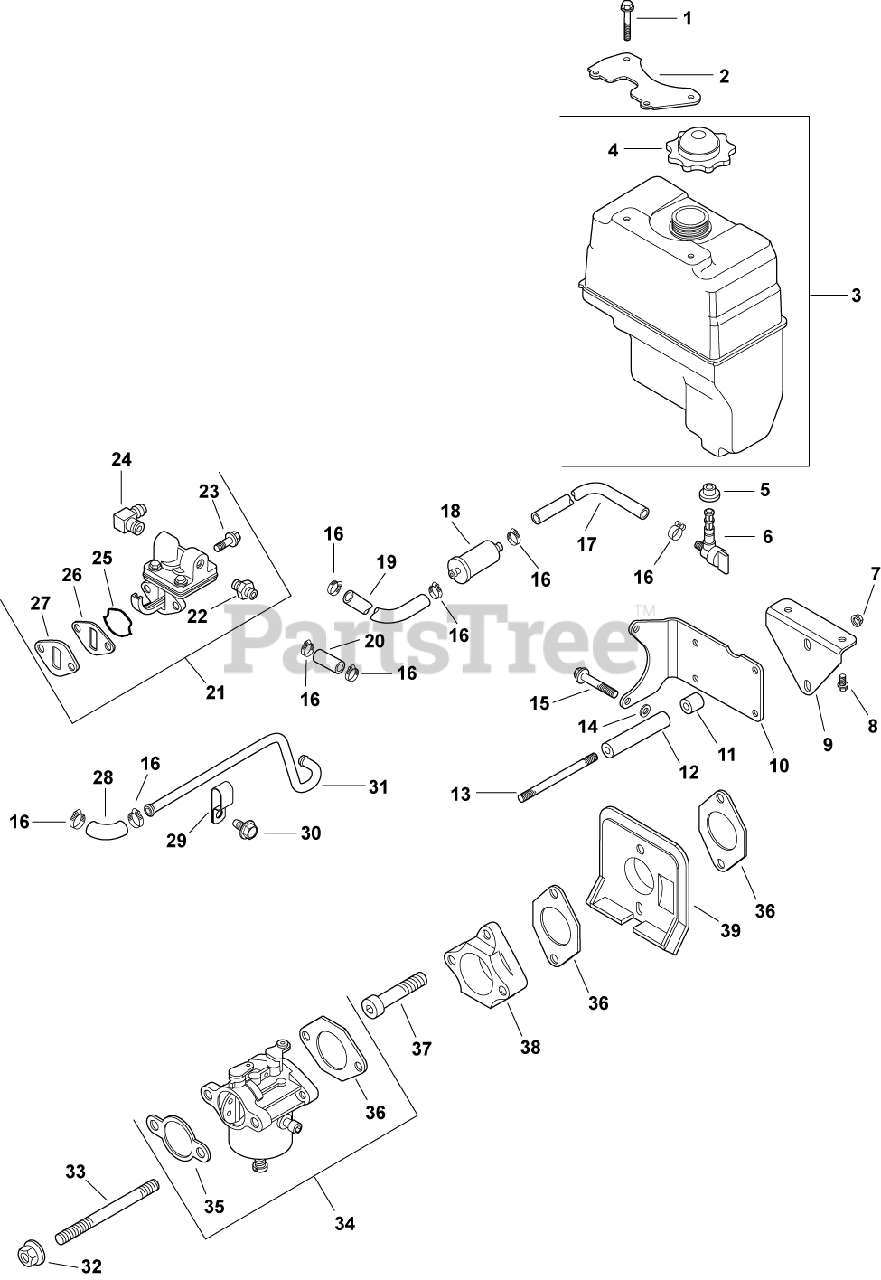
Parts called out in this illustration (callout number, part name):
1	SCREW,FLG THD FRM M6X1.0X25-(#25086395S)
2	BRACKET, FUEL TANK
3	KIT, FUEL TANK
4	CAP, FUEL TANK
5	BUSHING, FUEL TANK
6	VALVE, FUEL SHUT-OFF
7	NUT, FLG M8X1.25
8	SCREW, FLG M6X1.0X12
10	BRACKET, FUEL TANK
12	SPACER, FUEL TANK
13	STUD, M8X1.25X133-USE 25 755 54-S
14	WASHER, FLAT 11/32"
15	SCREW, FLG M8X1.25X50
16	CLAMP, HOSE (KM)-USE 25 237 31-S
17	LINE, FUEL 10"
18	FILTR,FUEL 75 MICRON (GRAVTY FEED)
19	LINE - DISCONTINUED
20	LINE - DISCONTINUED
21	KIT, FUEL PUMP
23	CONNECTOR
23	SCREW,FLG THD FRM M6X1.0X20-(#25086396S)
24	CONNECTOR, 90 DEG. HOSE
25	O-RING, FUEL PUMP
26	SPACER, FUEL PUMP
27	GASKET, FUEL PUMP
28	HOSE, FUEL LOW-PERMEATION
29	CLIP, TUBE & WIRING (KM)
30	SCREW, FLG THD FRM M5X.8X10
31	LINE, FUEL - DISCONTINUED
32	NUT, FLG M6X1.0
33	STUD,M6X1.0X116
34	KIT, CARBURETOR
35	GASKET, AIR CLEANER BASE
36	GASKET, CARBURETOR
37	SCREW, SKT CAP M6X1.0X35
38	ADAPTER, CARBURETOR
39	DEFLECTOR, HEAT
